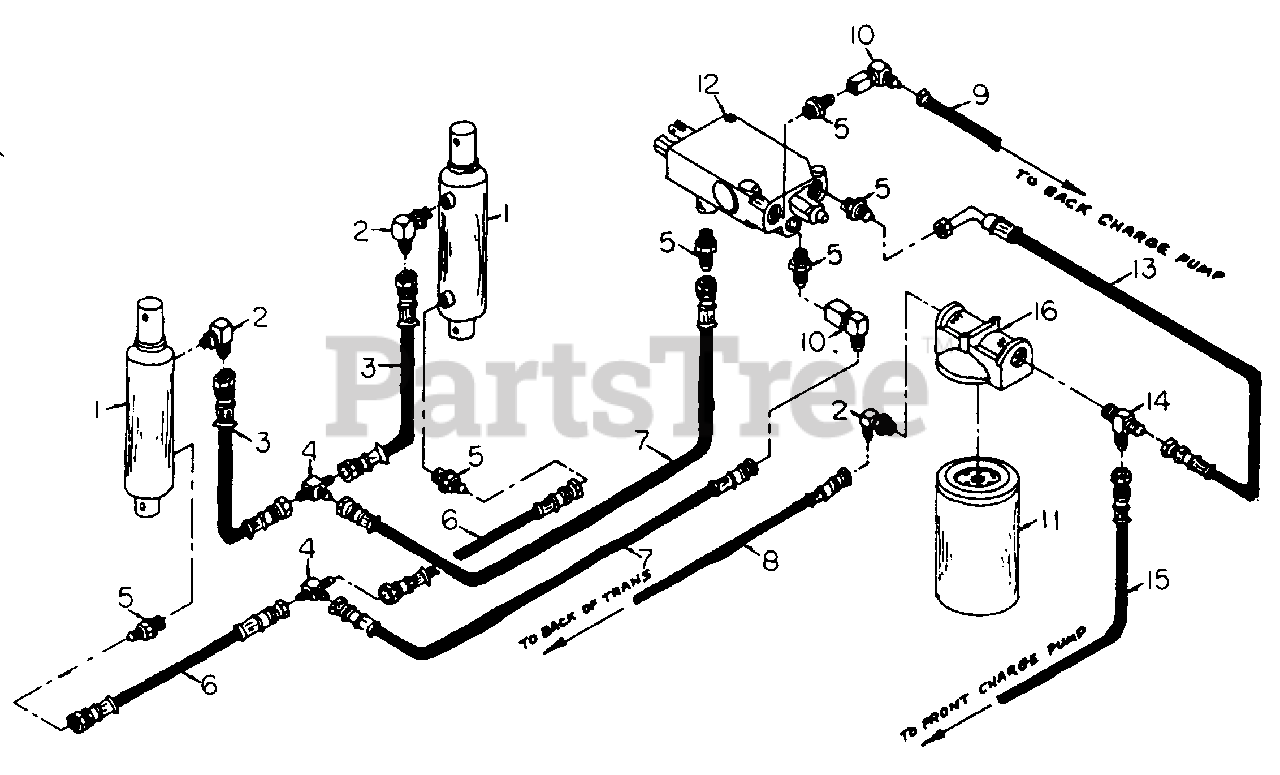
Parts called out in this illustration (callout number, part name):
1	Lift Cylinder
2	Male Tube, 90ø Adj. O-ring Adpt.
3	Hose, 3/8" x 12 1/2, Long
4	Male Tub Tee
5	Male Tube, Male O-ring Adpt.
6	Hose, 3/8" x 9" Long
7	Hose 3/8" x 52" Long
8	Hose, 3/8" x 11 1/2" Long
9	Hose, 3/8" x 42" Long
10	Male Tube, 90ø Female Swivel Adpt.
11	Filter Element
12	Valve Assembly
13	Hose, 3/8" x 21" Long
14	Male Tube, Male O-ring Tee
15	Hose, 3/8" x 30" Long
16	Housing, Oil Filter
